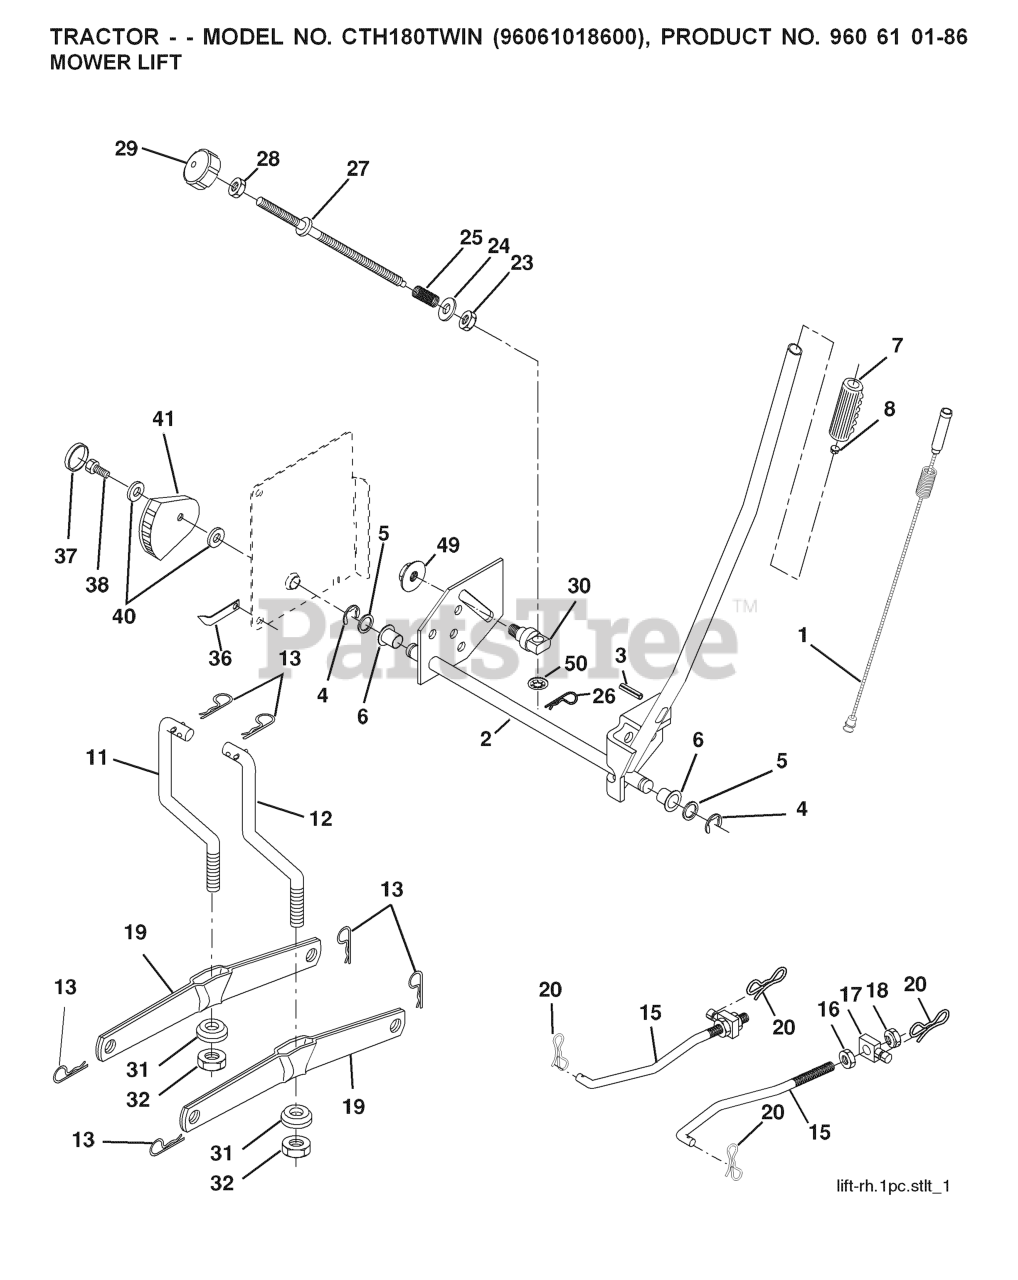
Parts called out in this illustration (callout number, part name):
2	SHAFT.ASM.LIFT.YT
3	PIN.GROOVE.5/16
4	RETAINING RING LT
6	BEARING.NYLON
7	GRIP HANDLE
8	REPL BY 532 12 59-25
11	LINK
12	LINK
13	RETAINER-SPRNG RB
15	LINK.SUSPENSION.FRONT
16	NUT.HEX.JAM.1/2-13
18	NUT.LK.W/WSH.1/2.
19	ARM.REAR.SUSPENSION
20	PIN.COTTER.7/16.BOW TI.
26	RETAINER CLIP
27	ROD ADJ LIFT
28	NUT
29	KNOB INF 3/8-16
31	BEARING.PIVOT.LIFT
32	NUT CROWNLOCK 3/8-24
36	POINTER, HEIGHT INDICATOR(2 2)
38	SCREW 5/16-18X1
41	HEIGHT INDICATOR
49	NUT
50	NUT PUSH M
